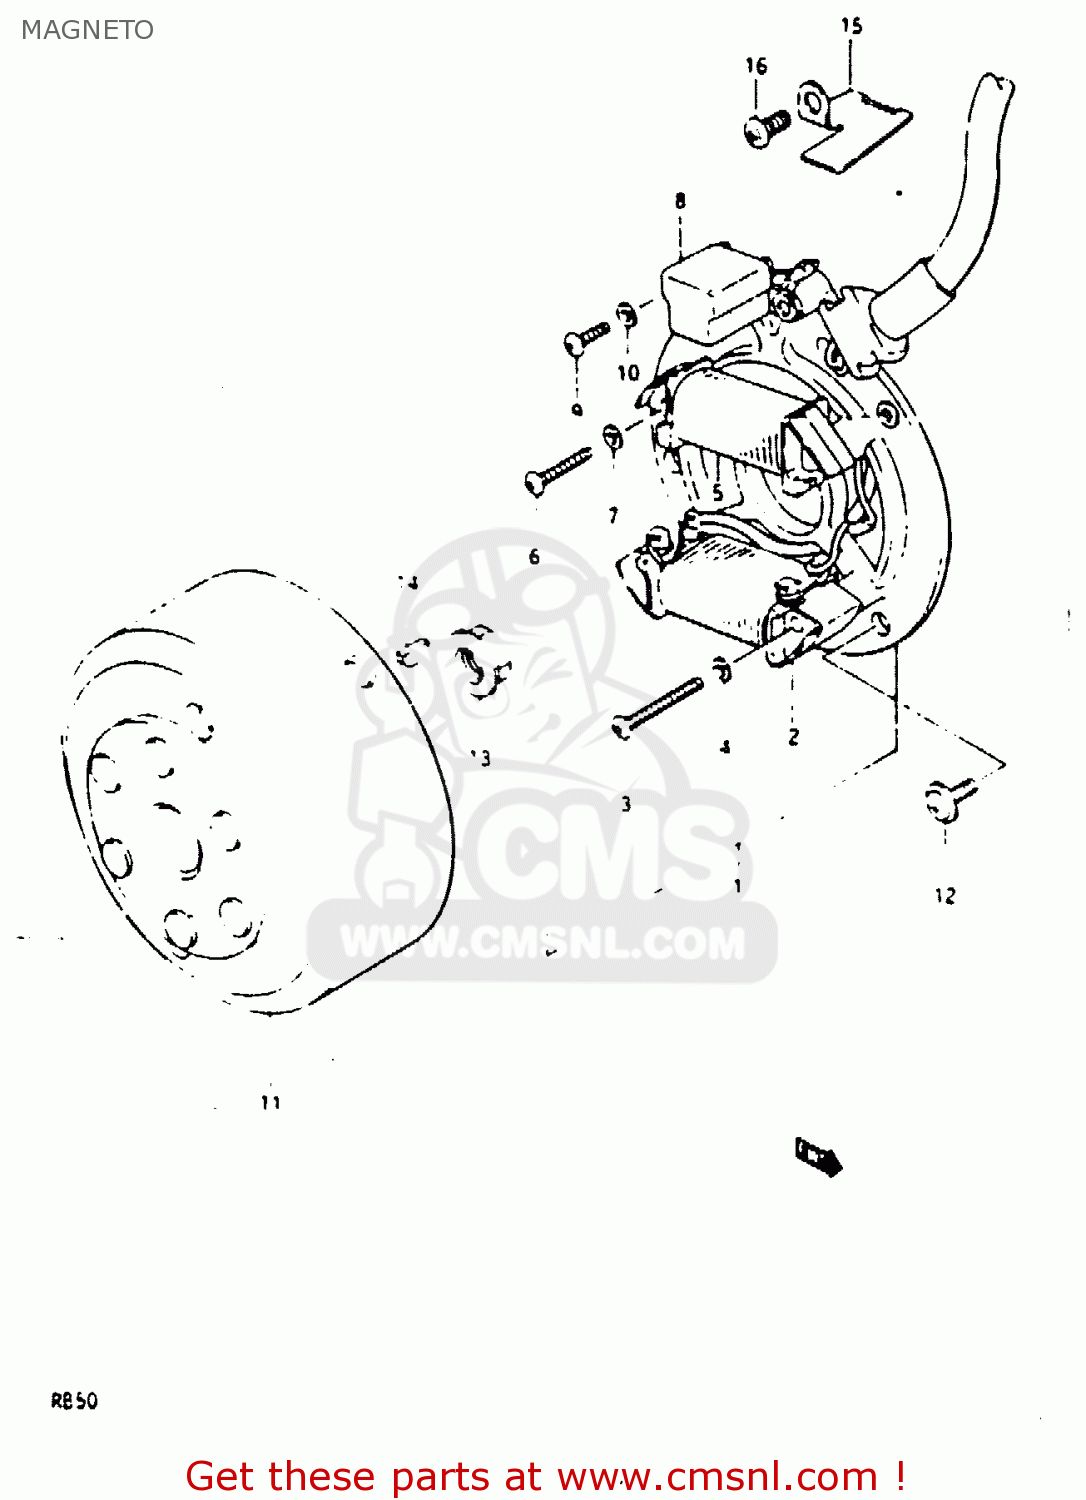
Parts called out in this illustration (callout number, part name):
1	STARTER ASSY
2	COIL,LIGHTING
3	SCREW (4X30)
4	WASHER,LOCK 4M
5	COIL,PRIMARY
6	SCREW
7	WASHER,LOCK 4M
8	COIL,PICK UP
9	SCREW
10	WASHER,LOCK 4M
11	ROTOR
12	SCREW
13	NUT
14	KEY
15	CLAMP,MAGNETO LEAD WIRE
16	SCREW
